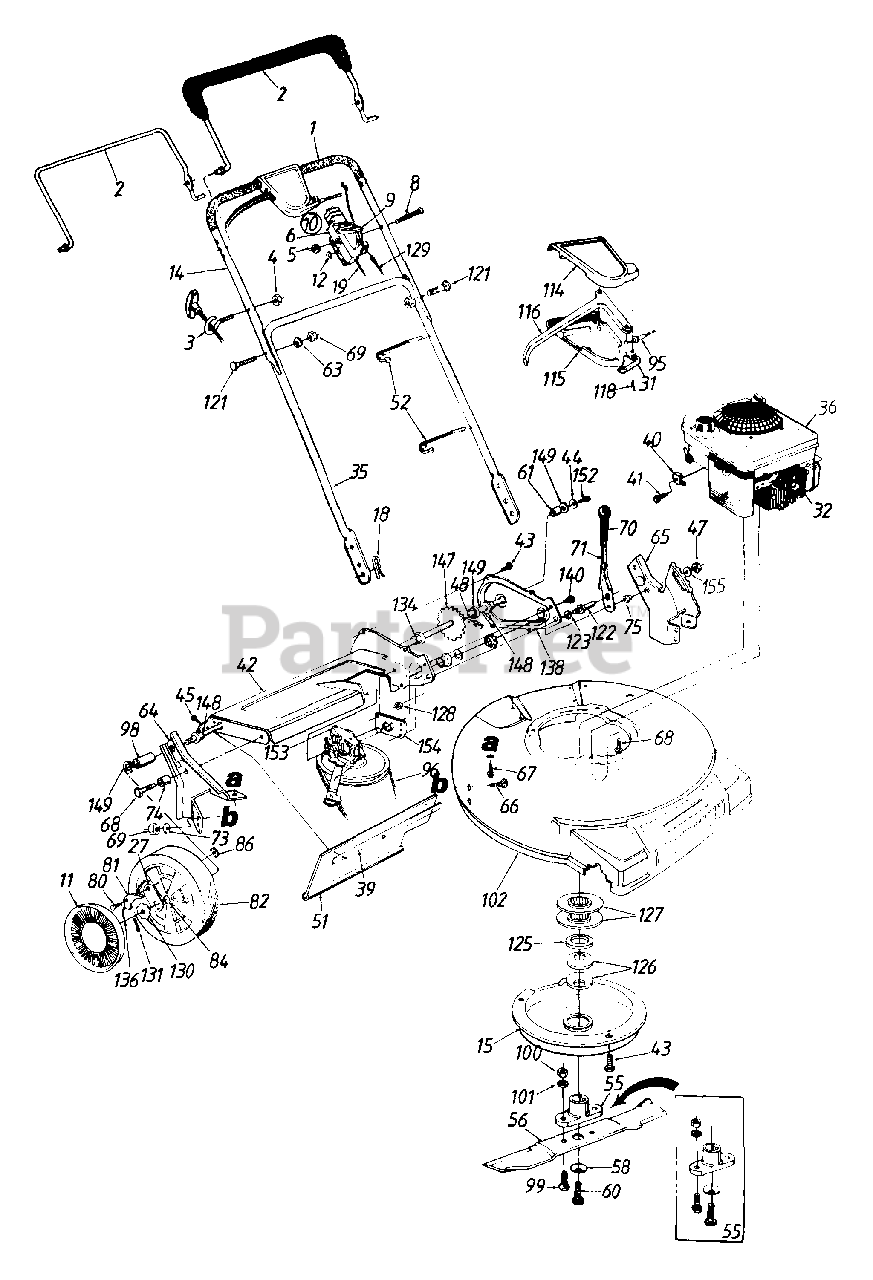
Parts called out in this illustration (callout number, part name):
1	Grip
2	Control Handle w/Plastic
3	Rope Guide
4	Hex L-Nut 1/4-20 Thd.
5	Hex L-Nut 1/4-20 Thd.
6	Throttle Body
8	Oval C-Sunk Scr.
9	Throttle Lever
10	Throttle Box Comp.
11	Hub Cap
12	Spr. Wash. .66" I.D.
19	Throttle Control Wire 55" Lg.
27	Pawl Plate
31	S.P. Control Cover
32	Spark Plug Insulator
35	Lower Handle
36	Engine
39	Retaining Strip
40	Cable Clamp
41	Hex Self-Tap Scr. #10-32 x .62"
42	Chain - Axle Ass'y.
43	Hex B-Tap Scr. 1/4" x .38"
44	Bell-Wash. 1/4" I.D.
45	Hex AB-Tap Scr. 1/4 x .62"
47	Hex Patch L-Nut 3/8-24 Thd.
48	#48 Chain .500" Pitch x 38 Links
51	Rear Flap 3.75" x 17.30" Lg.
52	Cable Tie
55	Blade Adapter Kit
56	21" Mulching Blade
58	Bell-Wash. .47" I.D. x 1.14" O.D.
60	Hex Bolt 7/16-20 x 2.5"
61	Spacer .513" I.D.
63	L-Wash. 5/16" I.D.
64	R.H. Handle Wheel Brkt. Ass'y.
65	L.H. Handle Wheel Brkt. Ass'y.
66	Carriage Bolt 5/16-18 x .62"
67	Hex B-Tap Scr. 5/16-18
68	Hex TT-Tap Scr. 3/8-16
69	Hex Nut 5/16-18 Thd.
71	Height Adj. Lever
73	Bell-Wash. 5/16" I.D.
74	Spacer 383" I.D.
75	Shld. Spacer .5" Dia.
80	Shld. Scr. .342" Dia. x .268
81	Pawl
82	Wheel Ass'y. Comp. - Rear 8" x 1.75" Bar Tread
84	Sleeve Bearing 1/2" I.D.
86	Weld Top L-Nut 1/4-20 Thd.
95	S.P. Cable - 44" Lg.
96	"V"-Belt
98	Sleeve .526" I.D.
99	Hex Bolt 3/8-24 x 1.0" Lg.
100	Hex Nut 3/8-24 Thd.
101	L-Wash. 3/8" I.D.
115	Self-Propelled Control Cover
116	Control Lever
118	Fl-"C"-Sunk Hd. Tap Scr. #10 x .75" Lg.
121	Curved Carr. Bolt 5/16-18 x 1.38" Lg
122	Shld. Pin 1.43" Lg.
123	L-Wash. 3/8" I.D.
125	Crankshaft Spacer
126	Bell-Wash. 1.01" I.D.
127	Pulley Half - Serrated
128	Hex Jam Nut 3/8-24 Thd.
129	Control Cable - 39"
130	Ratchet Wheel 1.62" O.D.
131	Cotter Pin 1/8" Dia. x 1"
134	Hex Flange Bearing
136	Spring - Nylon
147	Rear Shaft Ass'y. 21.44" Lg.
148	Hex Flange Brg. .506" I.D.
149	Fl-Wash. .531" I.D. x .930"
152	Hex Bolt 1/4-20 x .62" Lg. (Grade 5)
153	Transmission Comp.
155	Fl-Wash. .385" I.D. x .87" O.D.
